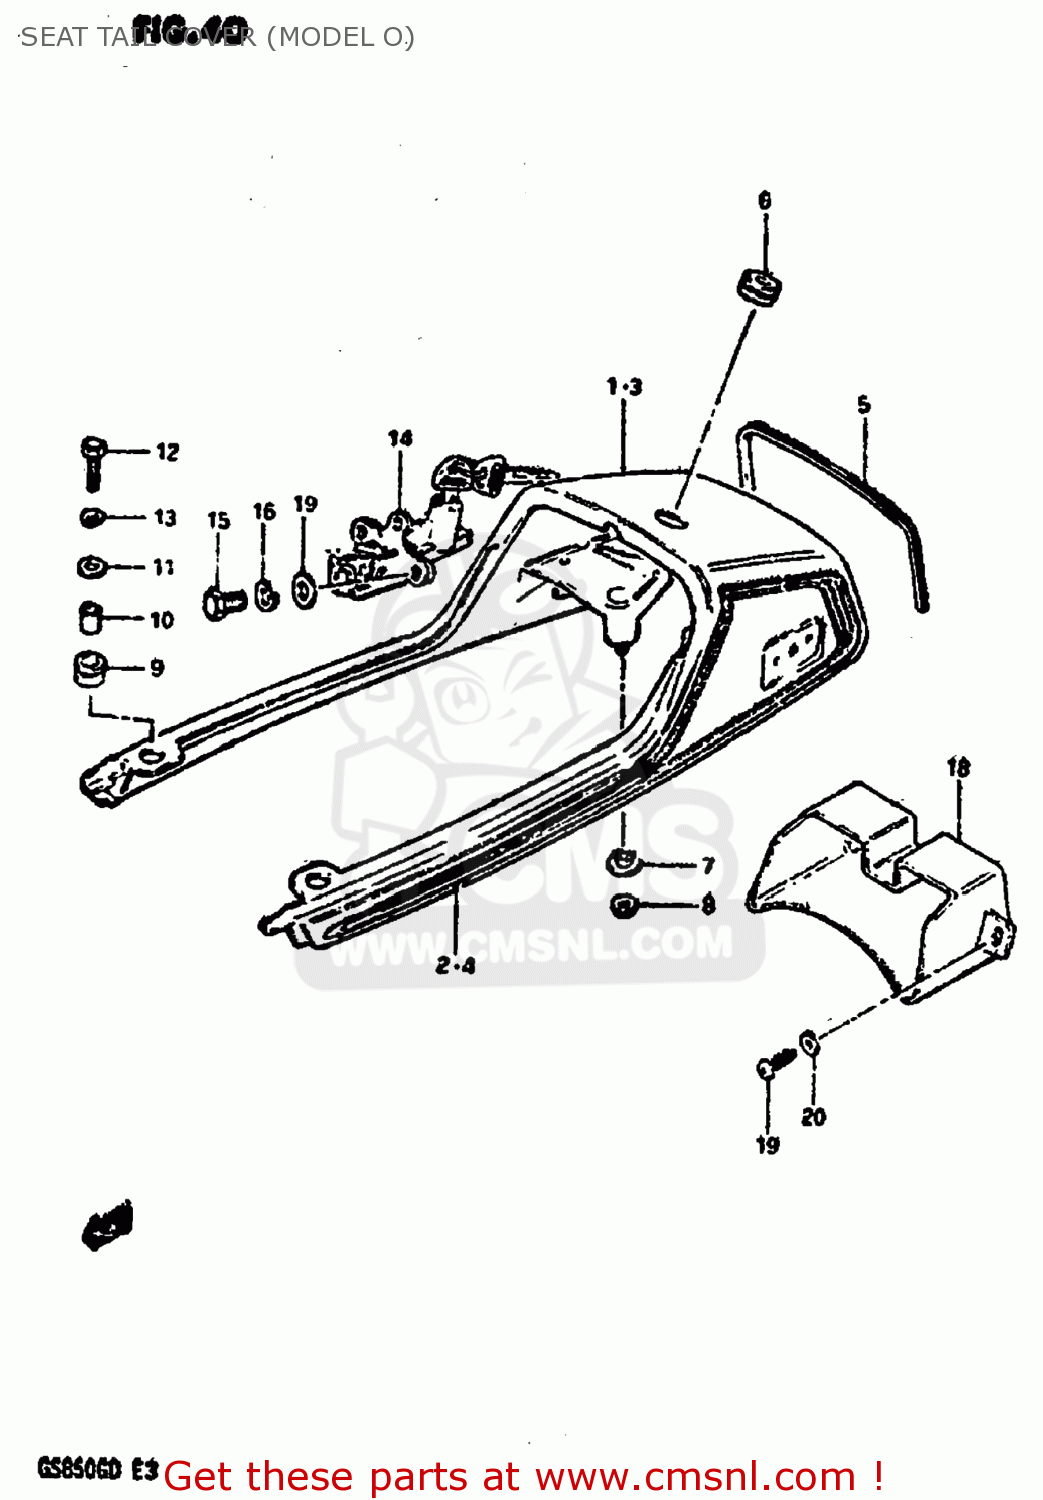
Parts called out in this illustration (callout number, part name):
1	BOX SET,SEAT TAIL
2	TAPE SET,SEAT TAIL COVER
3	BOX SET,SEAT TAIL
4	TAPE SET,SEAT TAIL COVER
5	MOLDING,SEAT TAIL COVER
6	GROMMET,SEAT LOCK HOLE
7	WASHER
8	NUT 6MM
9	CUSHION
10	SPACER (7X10X12)
11	WASHER (6.5X24X1.6)
12	BOLT
13	LOCK WASHER
14	LOCK SET,SEAT
15	BOLT
16	LOCK WASHER
17	WASHER
18	BOX, SEAT TAIL
19	SCREW
20	LOCK WASHER
